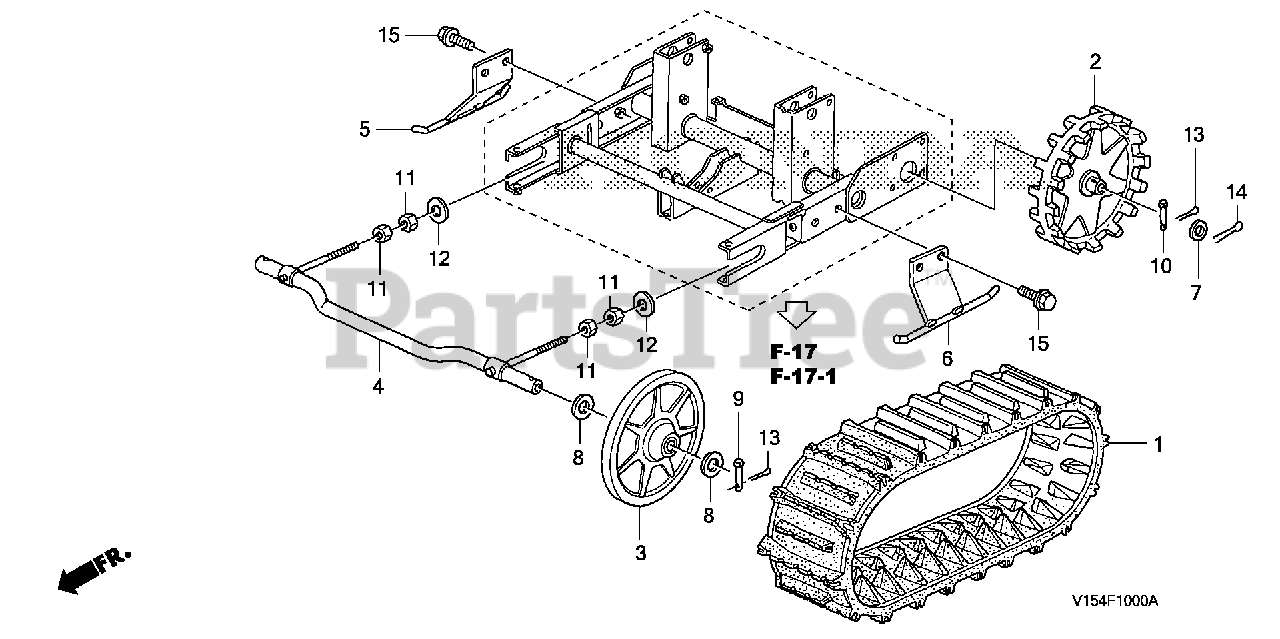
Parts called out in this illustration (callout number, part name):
1	CRAWLER (18-60X30 G-601) (COO)
2	SPROCKET, CRAWLER *NH31* (MCKINLEY WHITE)
3	ROLLER, CRAWLER *NH31* (COO) (MCKINLEY WHITE)
4	PIPE, CRAWLER
5	GUIDE, R. CRAWLER
6	GUIDE, L. CRAWLER
7	WASHER, PLAIN (26MM)
8	WASHER (29X45X2.3)
9	PIN, WHEEL
10	PIN (9X43)
11	NUT, HEX. (12MM)
12	WASHER, PLAIN (12MM)
13	PIN, SPLIT (2.5X30)
14	PIN, SPLIT (3.0X35)
15	BOLT, FLANGE (10X16)
